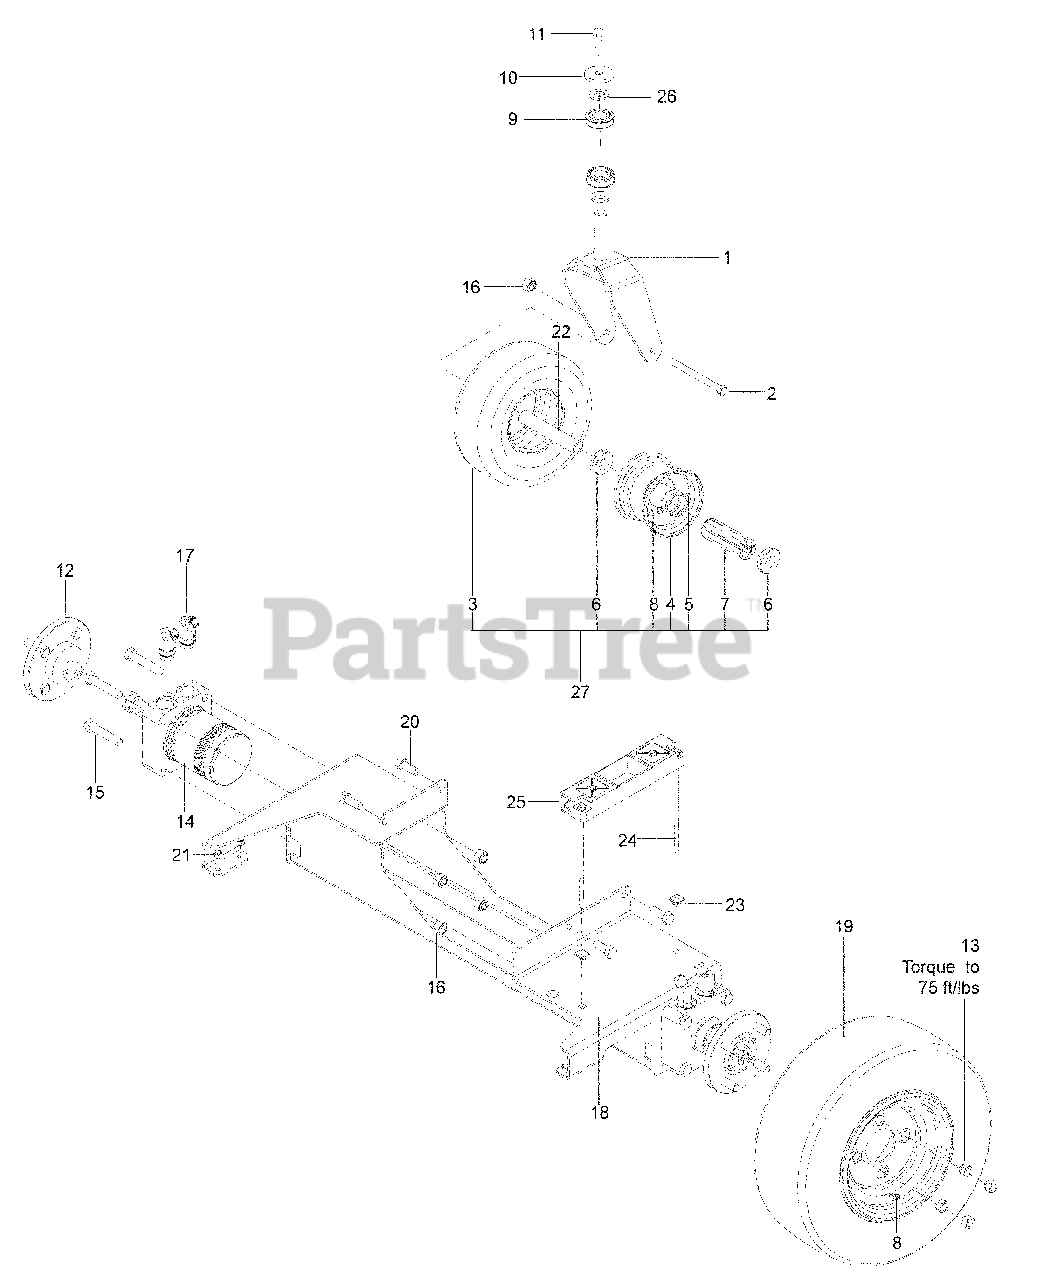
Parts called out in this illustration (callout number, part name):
1	CASTER FORK
2	HCS ½-13 x 5½
3	TIRE, CASTER
4	RIM, CASTER
5	ZERK
6	BEARING, FLANGE
7	ROLLER BEARING
9	BEARING
10	WASHER, HEAVY
11	HCS ½-13 x 1
12	HUB, WHEEL
13	NUT, LUG ½
15	HCS ½-13 x 2½
16	NUT ½ HEX NYLOC
17	ELBOW 45° STRAIGHT THD
19	WHEEL ASSEM, REAR
20	HCS ½-13 x 1¼
21	NUT 5/16-18 HEX NYLOC
23	PUSH NUT, NYLON
24	BOLT, ¼ x 7½
25	HOLD DOWN, BATTERY
27	WHEEL ASSEM, CASTER
